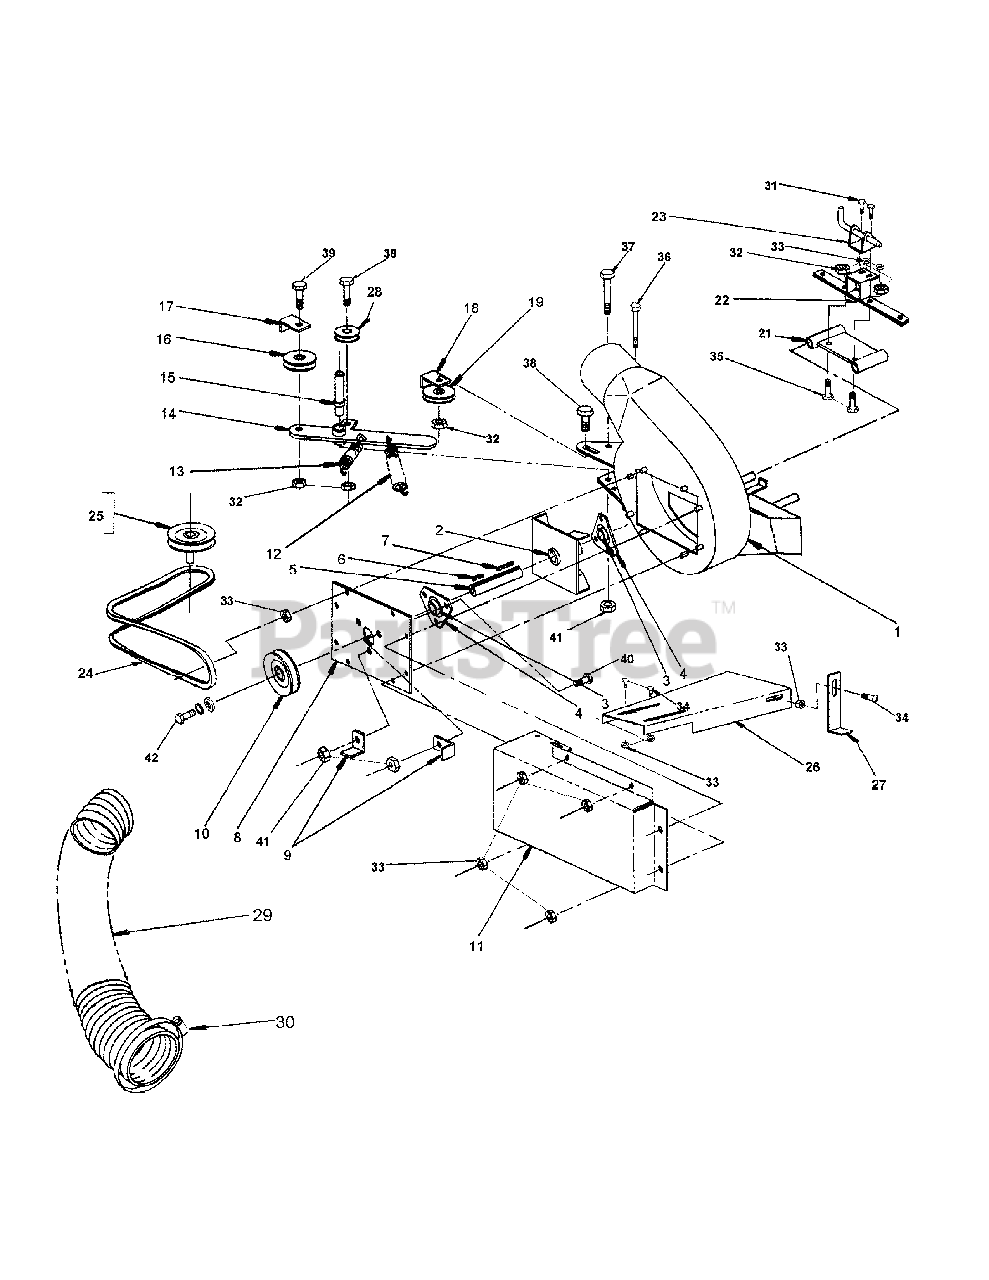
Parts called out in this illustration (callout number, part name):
1	Blower Housing
2	Fan
4	Flange, Bearing (set of 2)
5	Fan Shaft
6	1/4" x 3/4" key
7	1/4" x 1 1/4" key
8	Back Canister Cover
9	Fan Pulley Belt Bracket
10	Fan Drive Pulley
11	Blower Belt Cover
12	7/8" x 6" Spring
13	13/16" x 3 1/8" Spring
14	Idler Arm
15	Idler Arm Pivot
16	Flat Idler Pulley
17	Lower Pulley Bracket
18	Upper Pulley Bracket
19	V-Idler Pulley
21	Lower Mounting Bracket
22	Upper Mounting Bracket
23	Sprig Latch
24	87" A-sec. Belt
25	Drive Pulley
26	Belt Guard
27	Belt Guard
28	2.5" V-Idler Pulley
29	43" Urethane Hose
30	Hose Clamp
